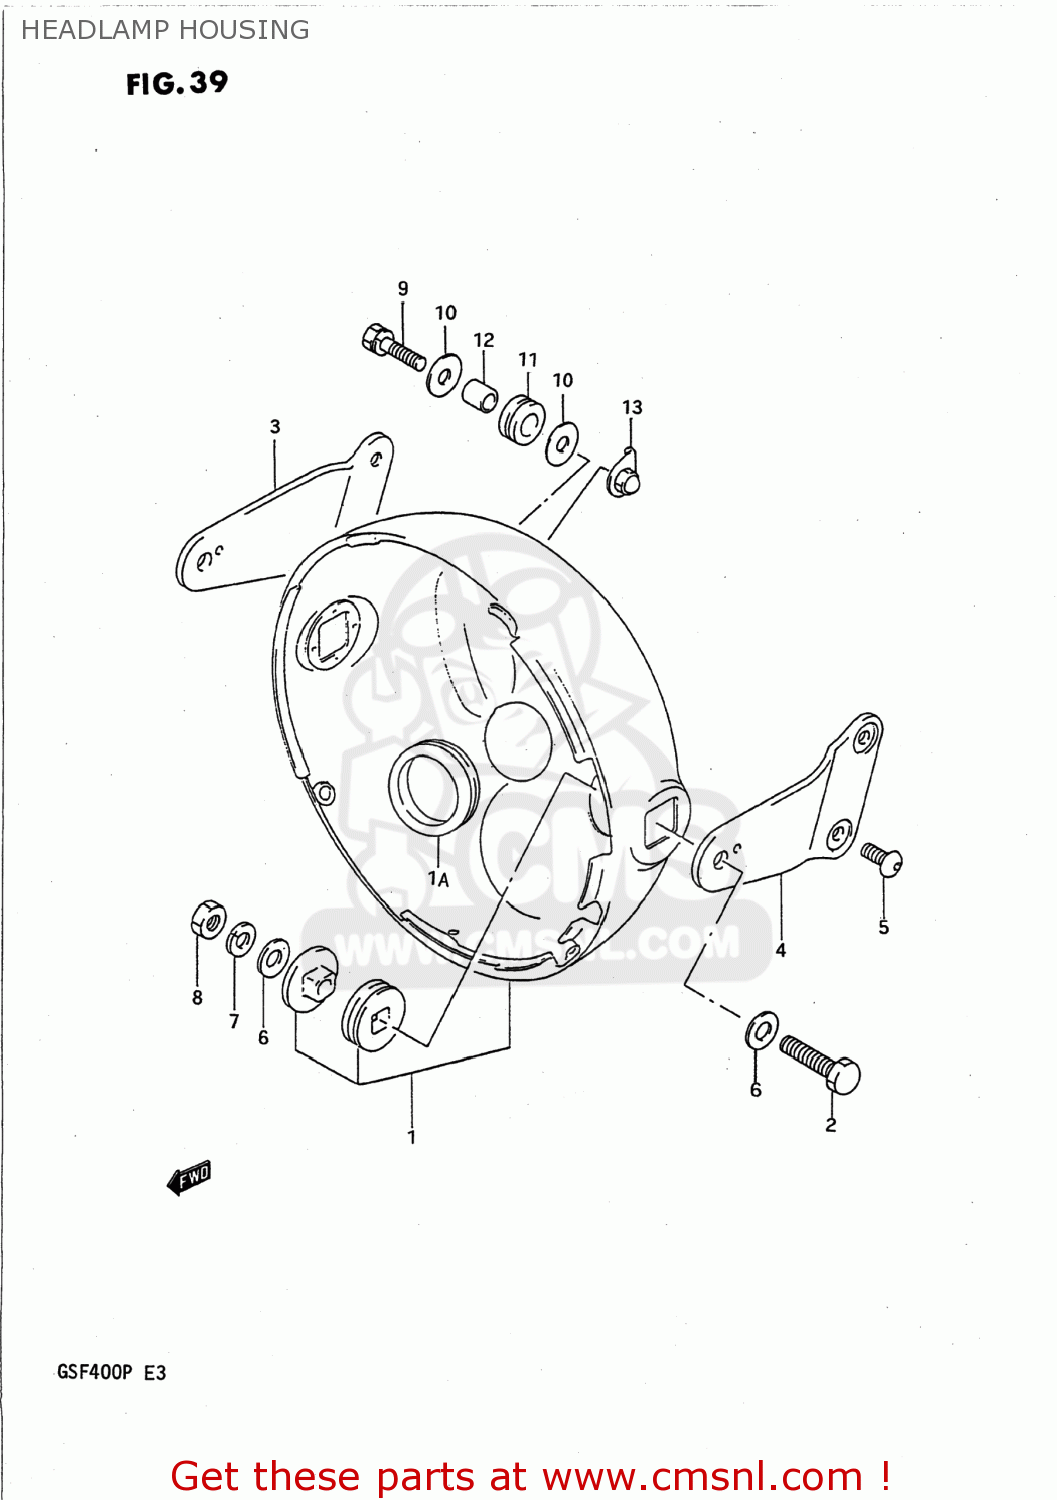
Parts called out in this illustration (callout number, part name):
1	HOUSING,HEADLAMP
1A	GROMMET
2	BOLT
3	STAY,HEADLAMP HOUSING,R
4	STAY,HEADLAMP HOUSING,L
5	SCREW(6X12)
6	WASHER
7	LOCK WASHER
8	NUT
9	BOLT
10	WASHER
11	CUSHION
12	SPACER(6.5X10.5X12)
13	PLATE,HEADLAMP
